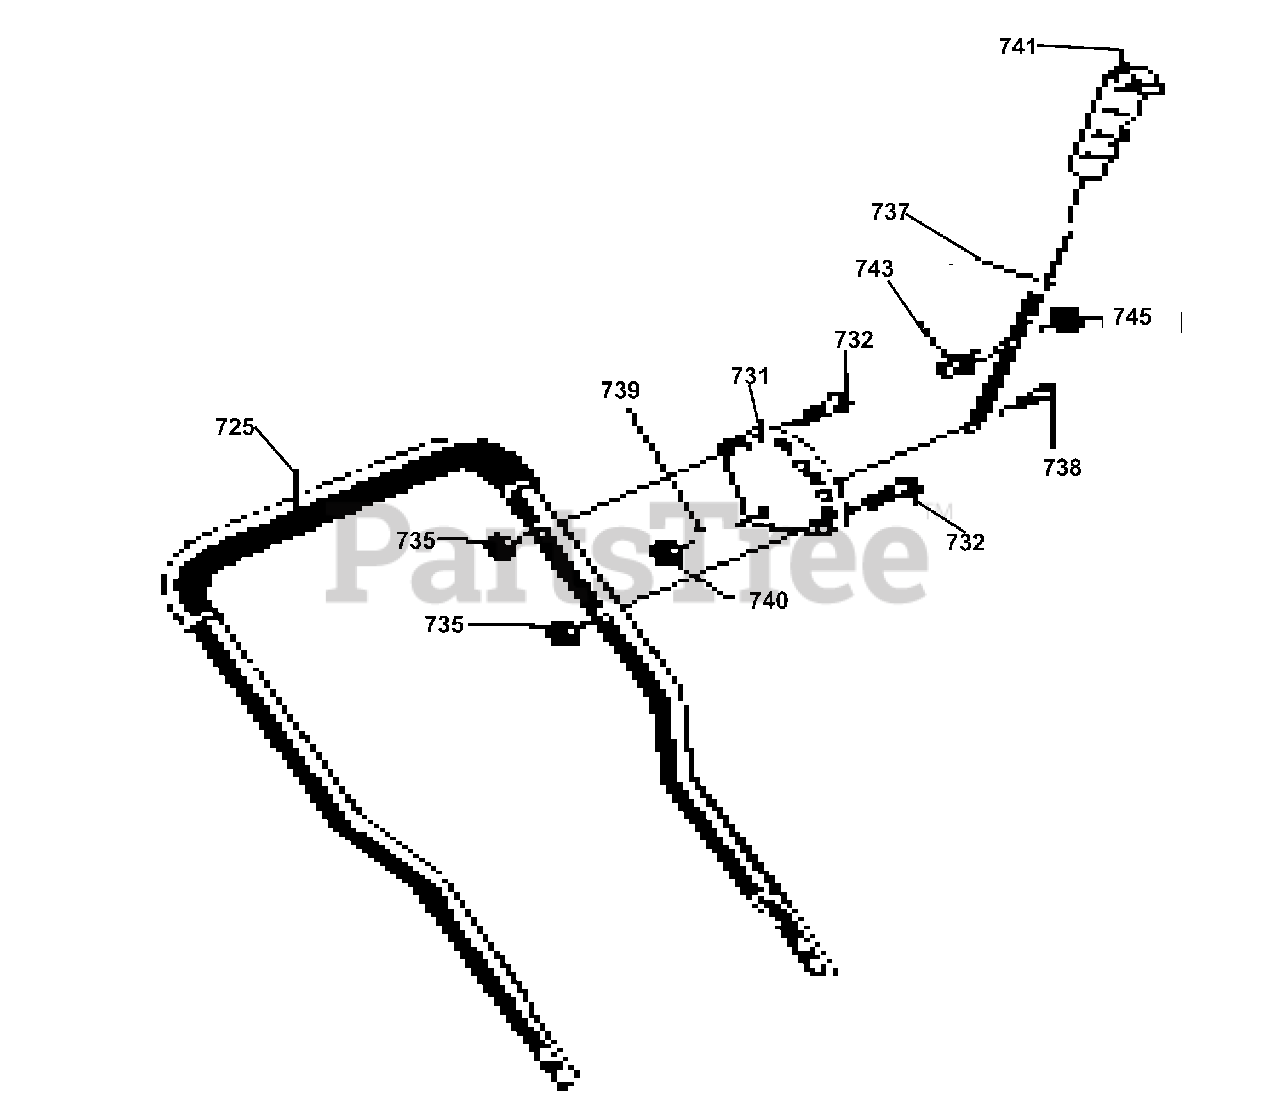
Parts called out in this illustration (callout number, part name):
725	Upper Handle & Foam
731	Plate Selector
732	Screw, 1/4-20x1.25
735	Nut, 1/4-20 Reghexctrlk
737	Handle, Depth Adjust
738	Screw, 5/16-18x1.25
740	Nut, 5/16-18 Reghexctrlk
741	Grip, Hand
745	Nut, 3/8-16 Reghexctrlk
